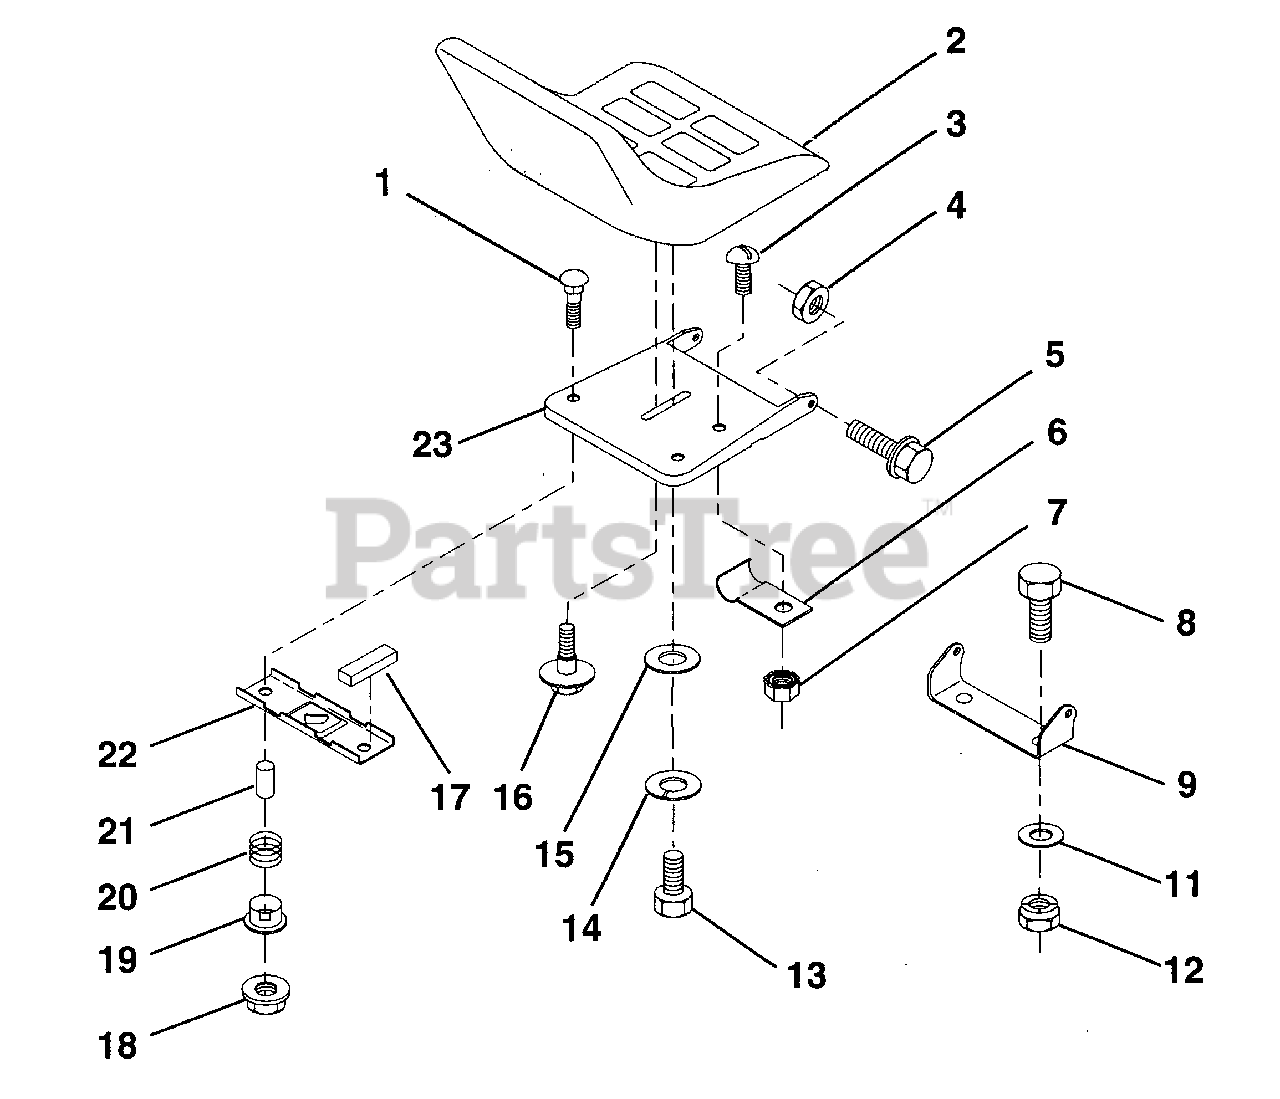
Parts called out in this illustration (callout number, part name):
1	Bolt, Carriage 1/4-20 x 1-3/8
2	Seat
3	Screw, Slotted Pan Head #10-32 x 1/2
4	Nut, Crown lock 5/16-18
5	Bolt, Shoulder 5/16-18 UNC
6	Clip, Insulated
7	Nut, Hex, Keps #10-32 UNF
8	Bolt, Hex, Fin. 3/8-16 UNC x 3/4
9	Bracket, Pivot, Seat
11	Washer 12/32 x 2 x 10 Gauge
12	Nut, Crown lock 3/8-16 UNC
13	Bolt, Hex, Fin. 1/2-13 UNC x 7/8 Grade 5
14	Washer, Lock, Heavy Helical Spring
15	Washer 17/32 x 1-3/16 x 12 Ga.
16	Bolt, Shoulder
17	Strip, Foam
18	Nut, Hex, Large, Flangelock
19	Bushing, Snap
20	Spring, Compression
21	Spacer, Split
22	Bracket, Switch Mounting
23	Pan, Seat
